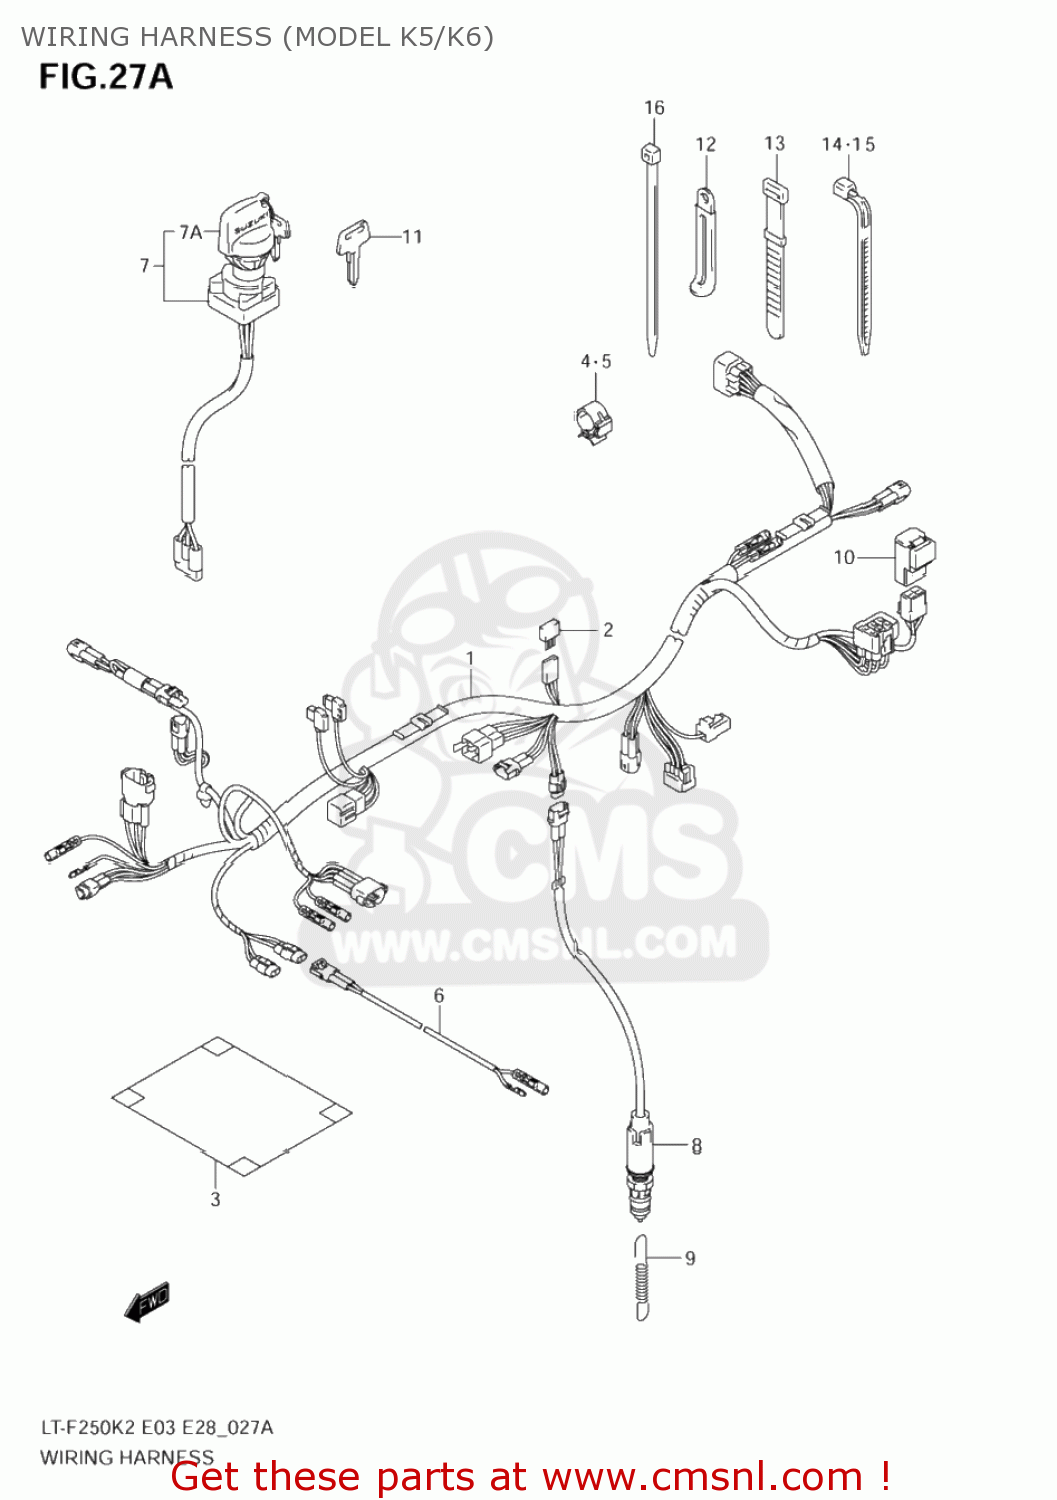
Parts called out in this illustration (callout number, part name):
1	HARNESS,WIRING
2	DIODE(STANLEY DE8804)
3	COVER,WIRING HARNESS
4	CLAMP
5	CLAMP
6	WIRE,BRAKE SW LEAD
7	SWITCH ASSY,IGNITION
7A	MASCOT,KEY
8	SWITCH ASSY,STOP LAMP
9	SPRING
10	RELAY ASSY
11	KEY,BLANK(TYPE:C)
12	CLAMP(L:45)
13	CLAMP(L:120)
14	CLAMP(L:125)
15	CLAMP(L:165)
16	CLAMP(L:100)
